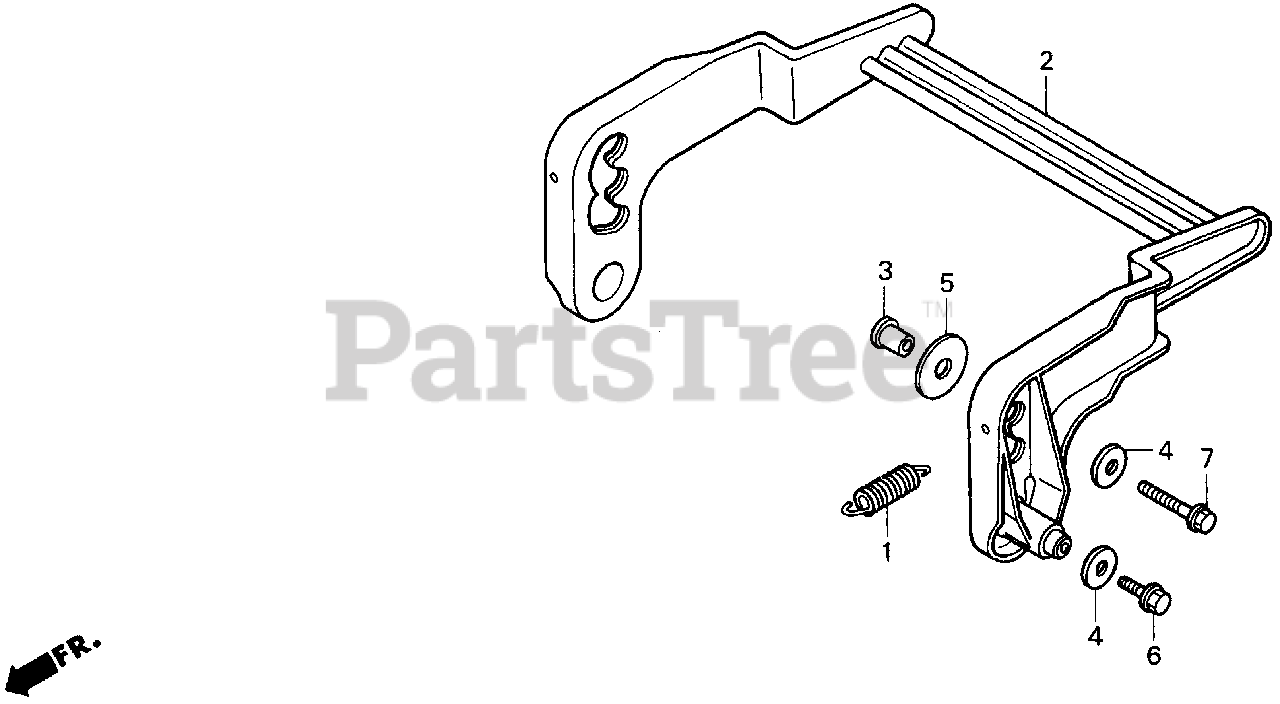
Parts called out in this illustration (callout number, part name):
1	SPRING, HEIGHT ADJUSTING
2	PLATE, HEIGHT ADJUSTING
3	COLLAR, HEIGHT ADJUSTING
4	WASHER, PLAIN (8MM)
5	WASHER, PLAIN (12MM)
6	BOLT, FLANGE (8X14)
7	BOLT, FLANGE (8X30)
